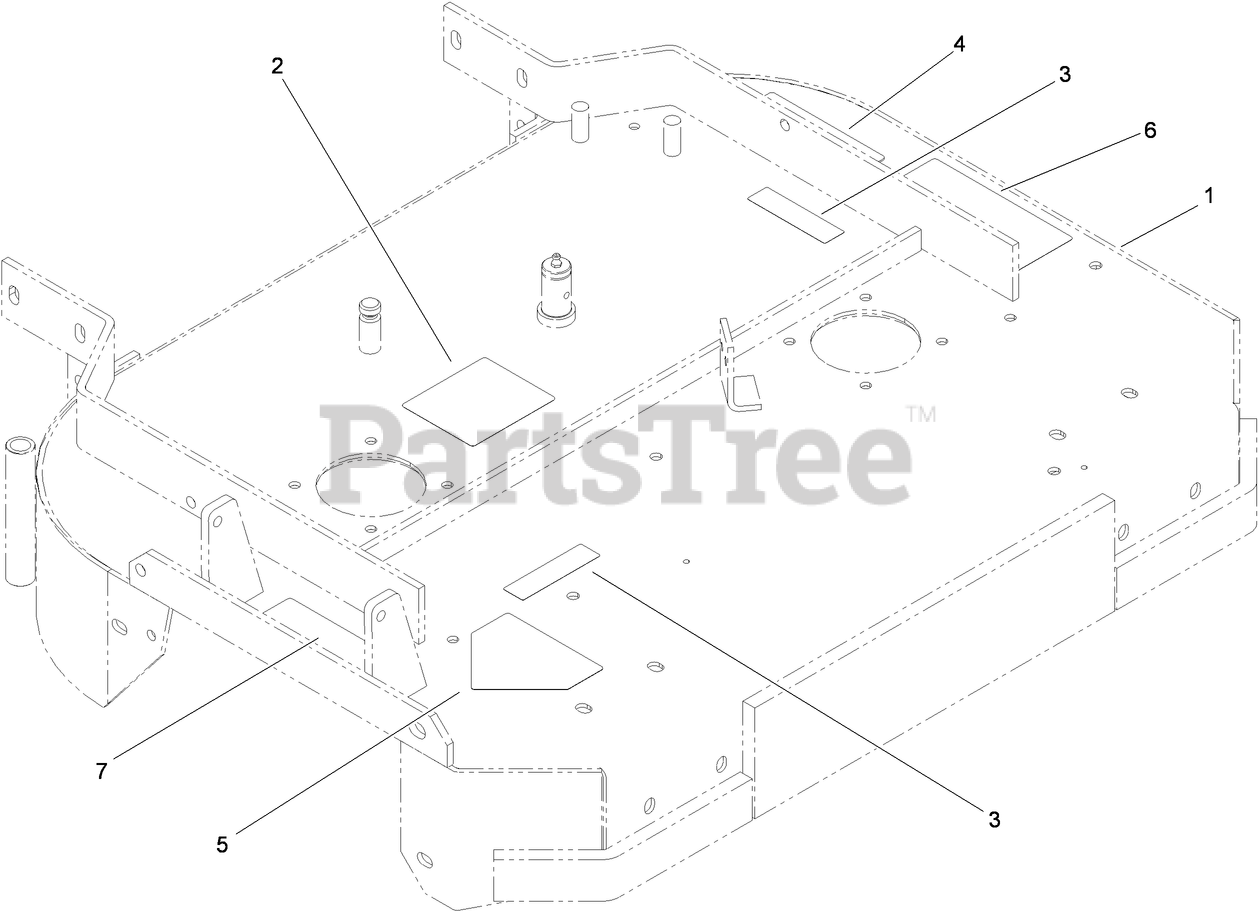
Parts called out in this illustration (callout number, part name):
1	Deck
2	DECAL-ROUTING, BELT
3	DECAL-COVER, MISSING
4	DECAL-TORQUE, BOLT
5	DECAL-DANGER
6	DECAL-DANGER, THROWN OBJECT
7	DECAL-WARNING
